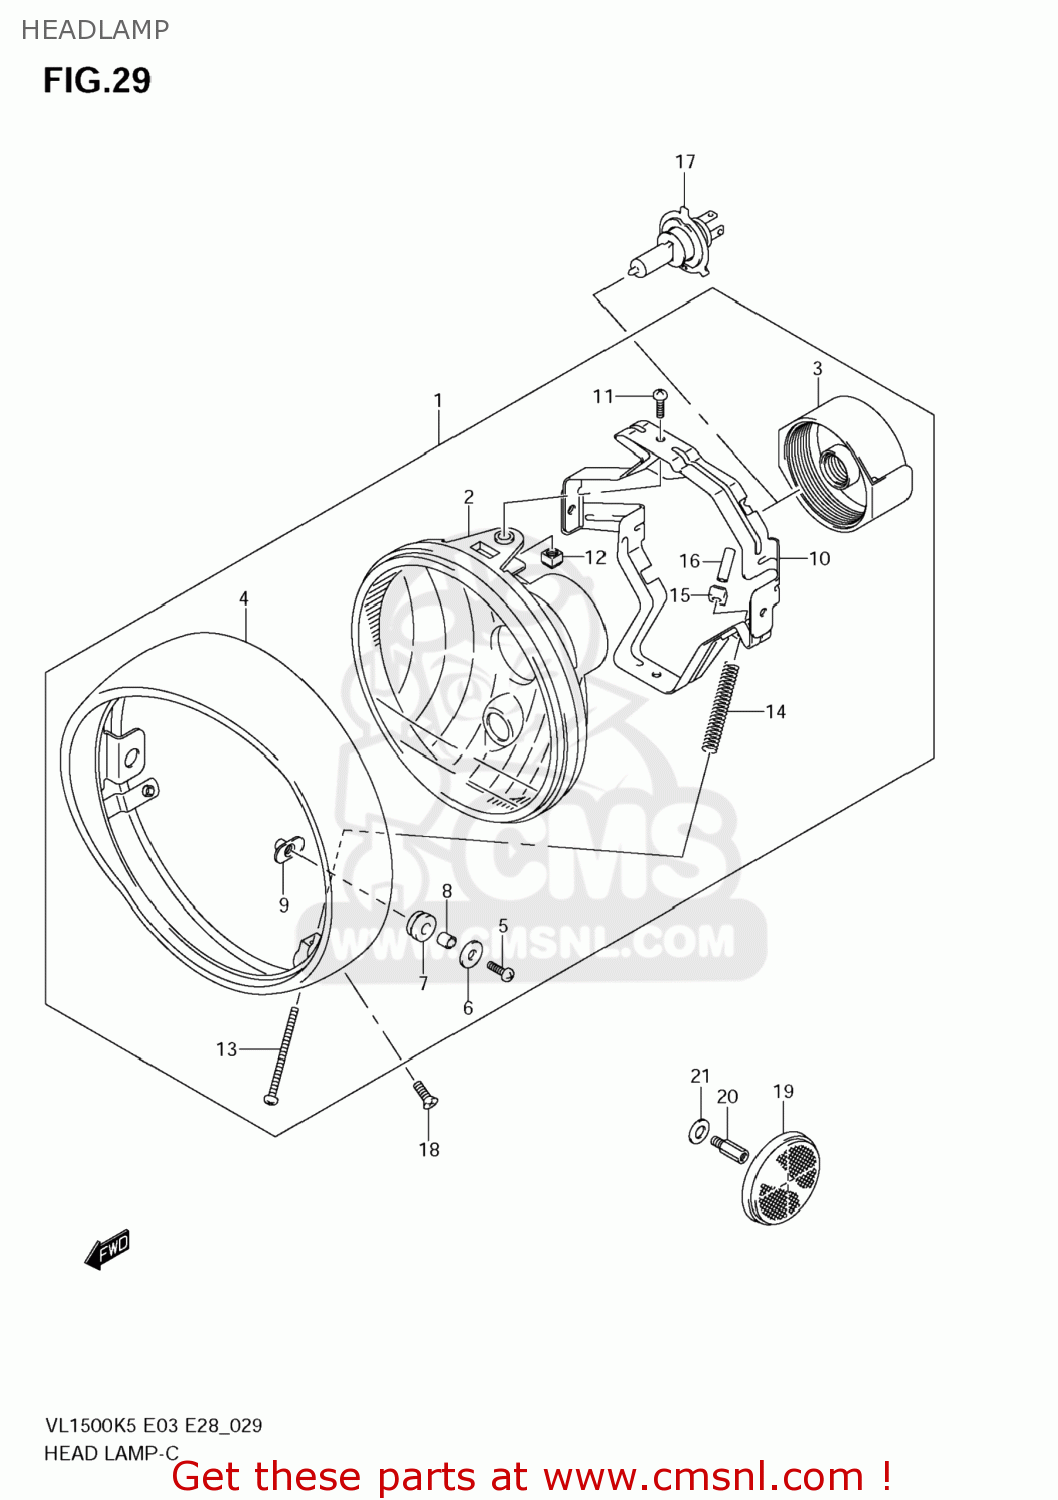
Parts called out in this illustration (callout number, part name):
1	HEADLAMP ASSY
2	UNIT
3	COVER,SOCKET
4	RIM
5	SCREW
6	WASHER(5.5X18X1)
7	CUSHION
8	SPACER
9	NUT
10	BRACKET
11	SCREW(5X16)
12	NUT
13	SCREW,ADJUSTER
14	SPRING,ADJUSTER
15	NUT,HEADLAMP ADJUST
16	COVER
17	BULB(12V60/55W,H4)
18	SCREW(5X8)
19	REFLEX REFLECTOR,RR
20	BOLT(5X10)
21	WASHER
